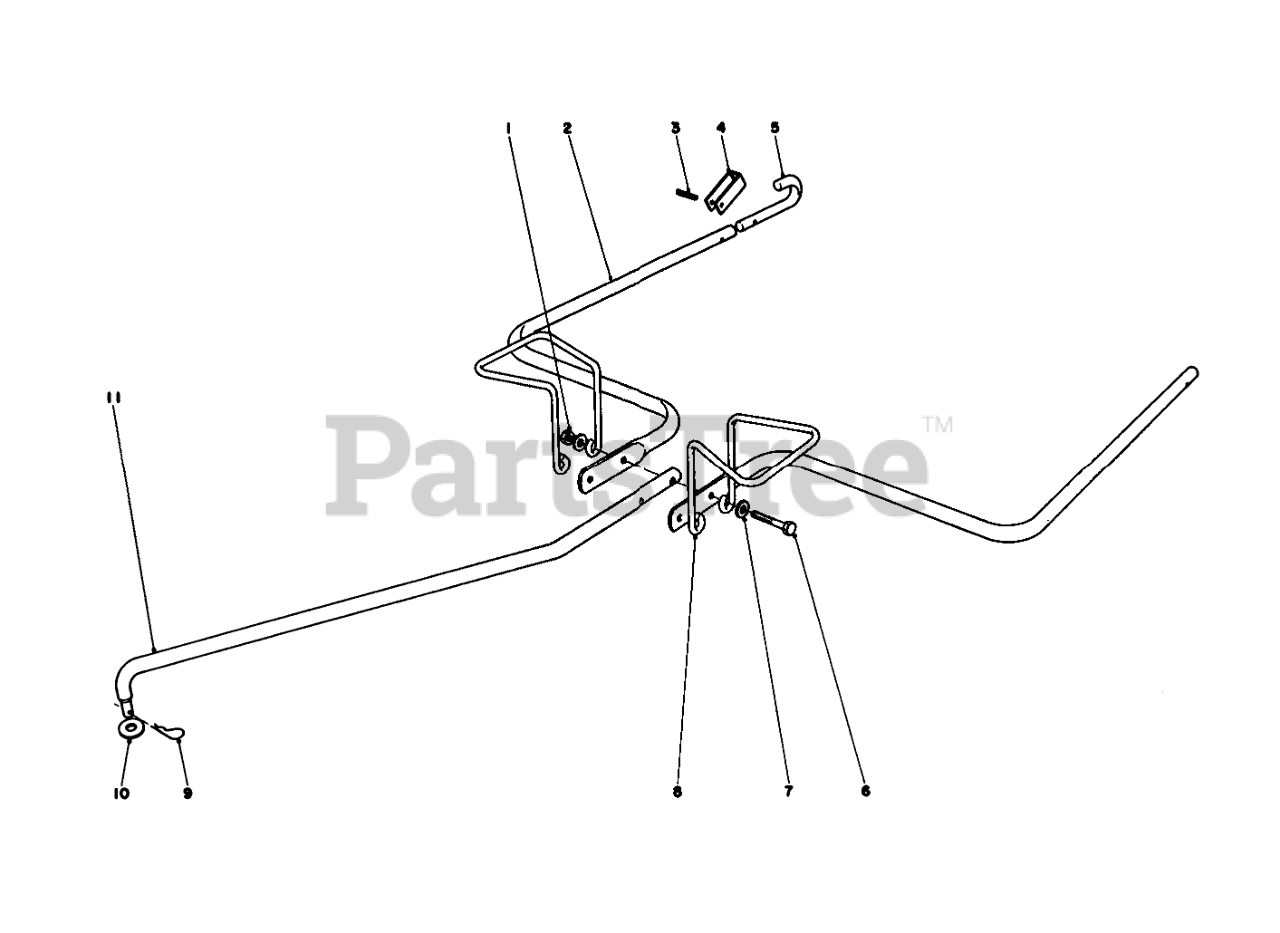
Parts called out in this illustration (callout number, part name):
2	HITCH ARM
3	PIN-ROLL, SLOT
4	HITCH LOCK
5	HOOK HITCH ARM
6	SCREW-HH
7	WASHER-FLAT
8	Support Bag
9	PIN-COTTER
10	PUSH NUT
11	POLE HITCH
